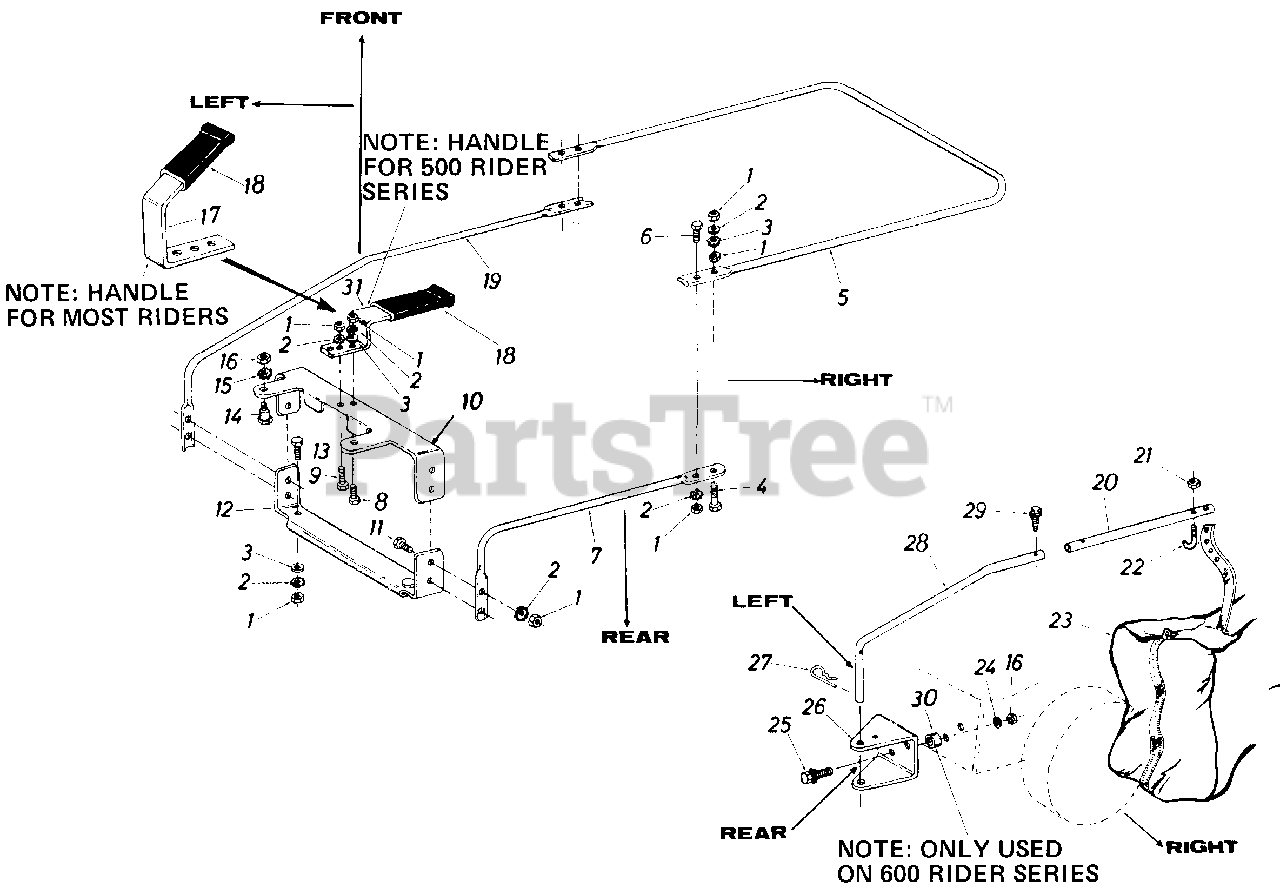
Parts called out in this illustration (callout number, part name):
1	Hex Nut 1/4-2 Thd.*
2	Ext. L-Wash. 1/4" Scr.*
3	Fl-Wash. .281 I.D. x .50 O.D.
4	Hex Scr. 1/4-20 x 1.50" Lg.*
5	Upper Frame Half
6	Hex Scr. 1/4-20 x 1.00" Lg.*
7	Lower FrameTubing
8	Hex Scr. 1/4-20 x .75" Lg.
9	Hex Scr. 1/4-20 x .75" Lg.*
10	Upper Opening Support
11	Hex Scr. 1/4-20 x 1.0" Lg.*
12	Lower Opening Support
13	Hex Scr. 1/4-20x.50" Lg.*
14	Shld. Scr. .437 Dia. x .350
15	Ext. L-Wash. 5/16" Scr.*
16	Hex Nut 5/16-18 Thd.*
19	Lower Frame Arm
23	Grass Catcher Bag
24	L-Wash. 5/16" I.D.*
25	Hex Sems Scr. 5/16-18 x .75" Lg.*
26	Hitch Bracket
27	Internal Cotter Pin 5/8" Dia.
28	Lower Holding Arm
29	Hex Wash. Hd. Self-Tap .50" Lg.
30	Spacer
31	Handle
